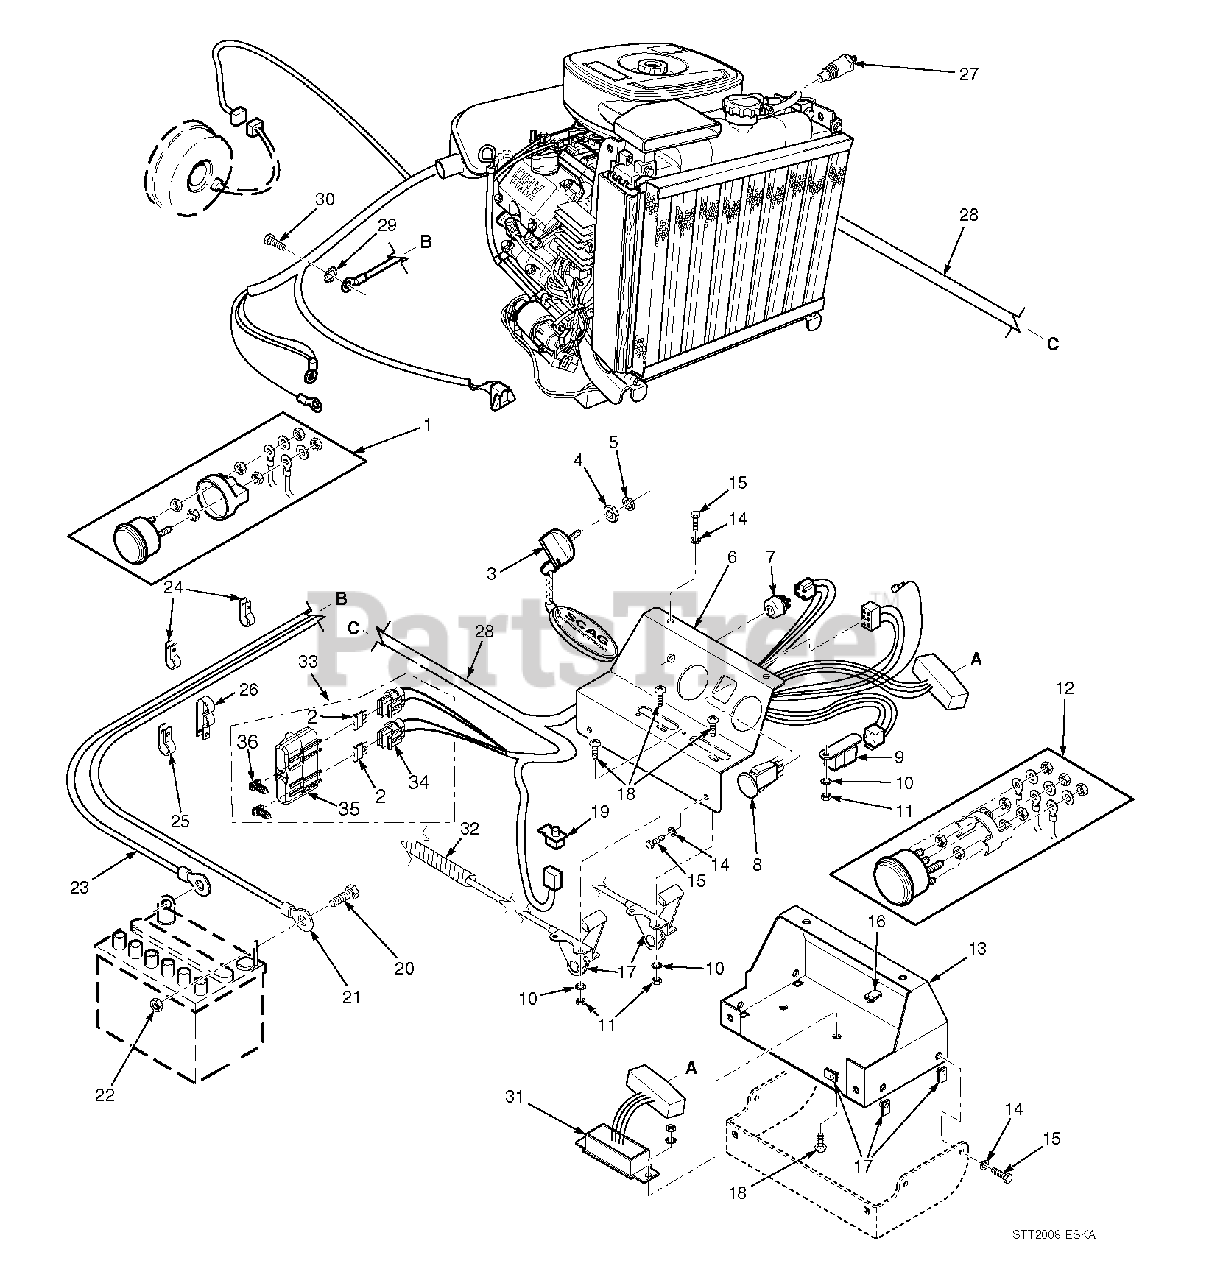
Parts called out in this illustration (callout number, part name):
1	Ammeter
2	Fuse, 20 AMP
3	Key, Ignition
4	Nut, Hex 5/8-32
5	Lockwasher, 5/8" Internal
6	Instrument Panel, Top w/Decals
7	Key Switch
8	Switch, PTO
9	Relay
10	Lockwasher, #10 External Tooth
11	Nut, Hex #10-32
12	Water Temp. Gauge
13	Base, Instrument Panel
14	Lockwasher, 1/4"
15	Bolt, Hex Head 1/4-20 x 3/4"
16	U-Nut, 1/4-20
17	Throttle And Choke Controls
18	Screw, Phillips Washer Head #10-32 x 1/2"
19	Switch, Interlock-Seat
20	Bolt, Hex Head 1/4-20 x 1/2"
21	Cable, Battery - Red
22	Nut, Hex 1/4-20
23	Cable, Battery - Black
24	Clamp, Cable 1/2" ID.
25	Clamp, Cable 3/4" ID.
26	Clamp, Cable
27	Sending Unit, Water Temp.
28	Wire Harness, STT
29	Lockwasher, 5/16" External Tooth
30	Bolt, Hex Head M8-1.25 x 20mm
31	Electronic Module
32	Heatshield, Flexible
33	Double Fuse Assembly, Sealed
34	Fuse Holder
35	Cover, Sealed Double
36	Clip, Wire
